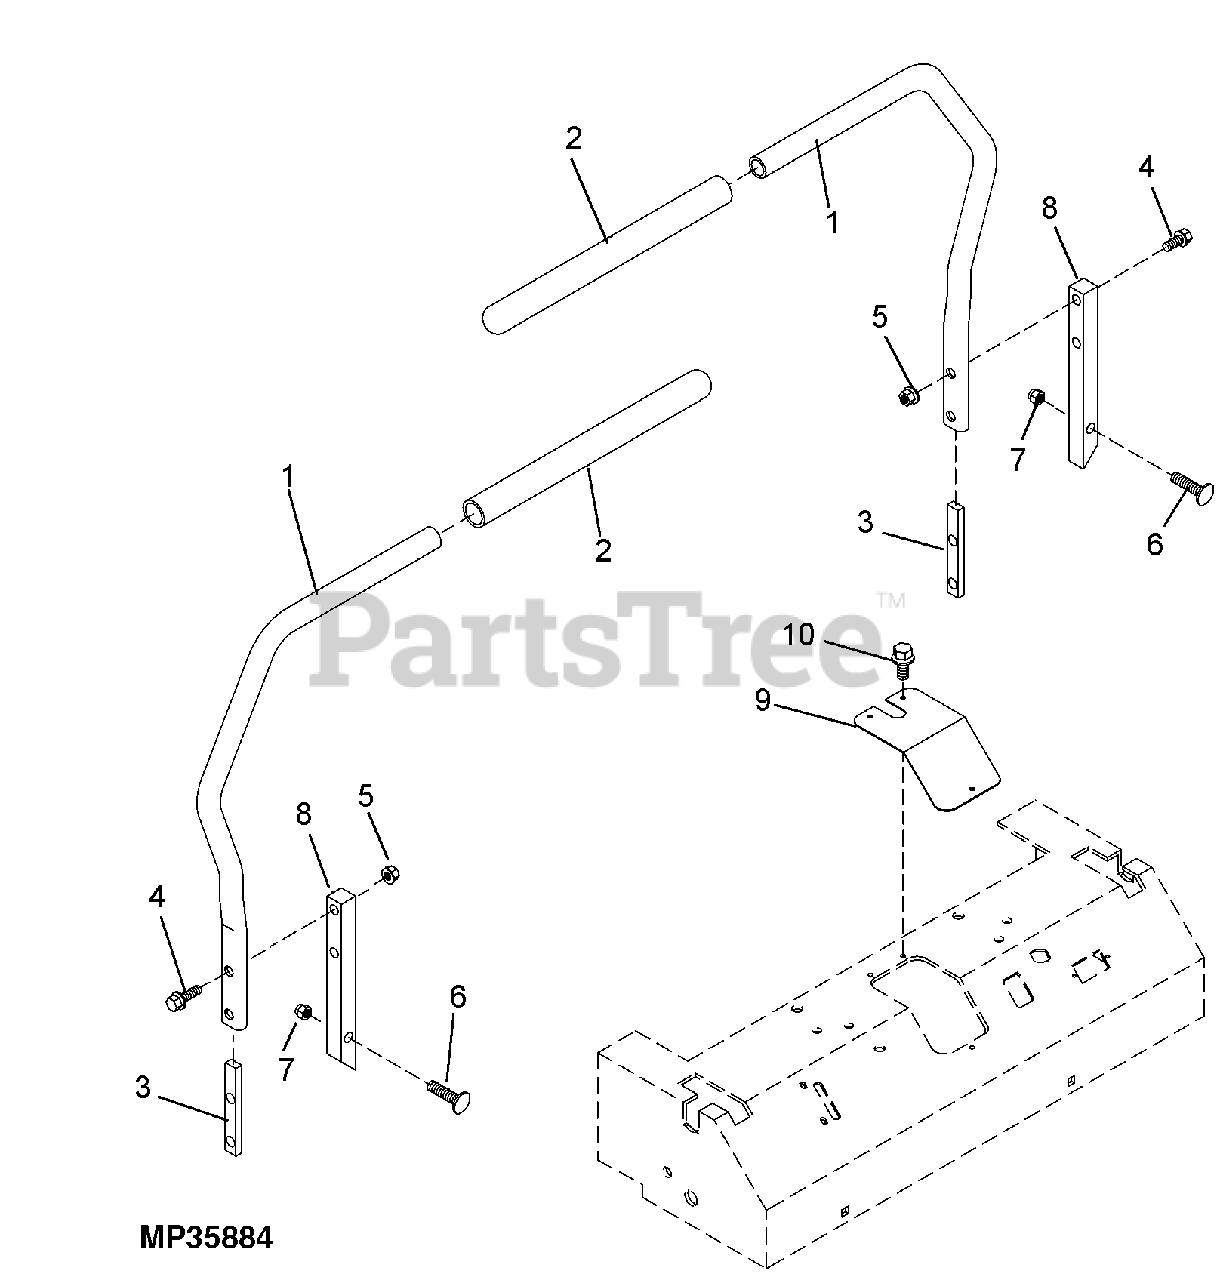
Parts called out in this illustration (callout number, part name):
1	TUBE CONTROL ARMS
2	GRIP, FOAM
4	SCREW, FLANGED, METRIC
5	LOCKNUT,FL,ISO7044,M10X1.5-10-
6	BOLT,RH,SQNECK,JDS137,M10X1.5X
7	LOCK NUT M10
8	ARM, CONTROL - SQUARE
9	COVER, CONSOLE
10	SCREW,SELFT,FL,JDS145,M5X.8X12
